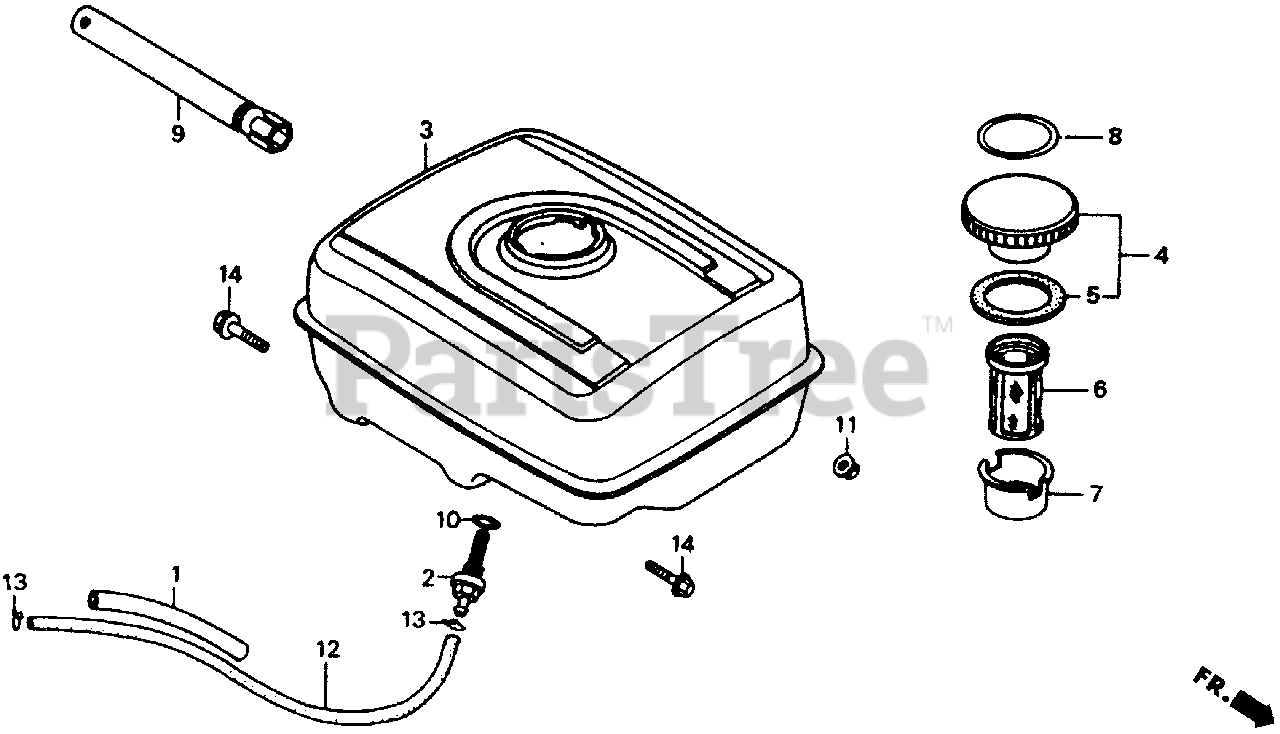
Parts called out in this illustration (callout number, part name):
1	RUBBER, SUPPORTER (107MM)
2	JOINT, FUEL TANK
3	TANK, FUEL *NH31* (MCKINLEY WHITE)
4	CAP, FUEL FILLER
5	GASKET, FUEL FILLER CAP
6	FILTER, FUEL
7	HOLDER, FUEL FILTER
8	MARK, CAUTION (EXTERNAL)
9	WRENCH, SPARK PLUG
10	O-RING (13.5X1.5) (ARAI)
11	NUT, FLANGE (8MM)
12	BULK HOSE, FUEL (4.5X3000) (4.5X235)
13	CLIP, TUBE (B8)
14	BOLT, FLANGE (8X25)
